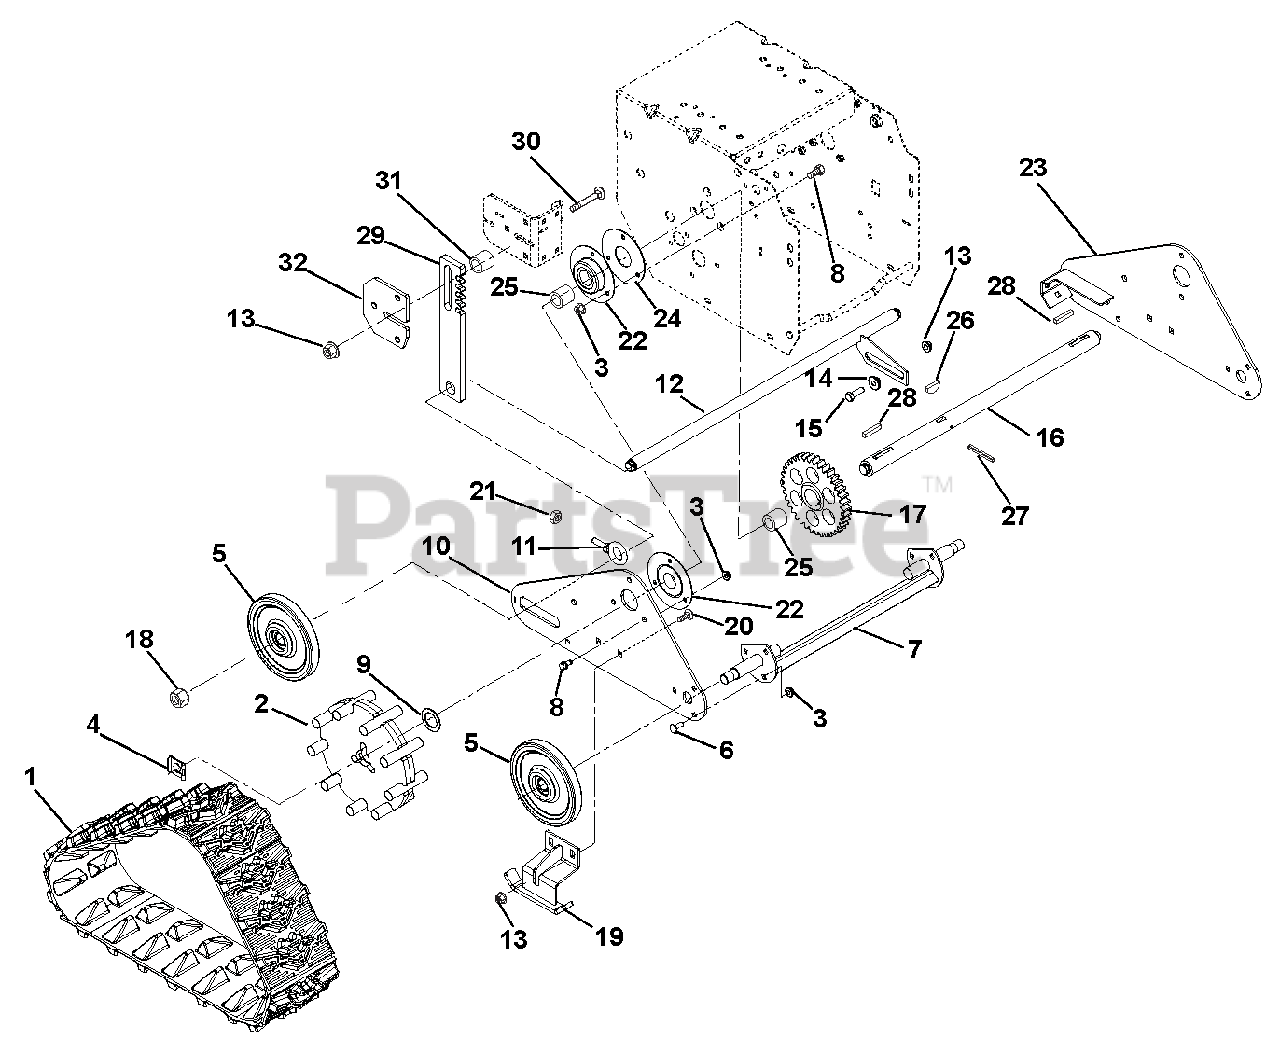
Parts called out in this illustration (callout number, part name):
1	TRACK, RUBBER
2	WHEEL, DRIVE-TRACK
3	@NUT-LK-TOP-FLG .25-20 YWZC
4	CLIP, SNAP .625 DIA
5	WHEEL, BOGIE - SINGLE BEARING
6	@BLT-RDHDSQNK .25-20X.75 G5YZ
7	AXLE, FRONT-DELUXE TRACK
8	@BLT-HEX .25-20X.75 GR5 YWZC
9	WSHR-FL-STL 1.010X1.505X.062YZ
10	SIDE PLATE, RH-DELUXE TRACK
11	BLT-EYE .375-16X.880 YWZC
12	AXLE, REAR - DELUXE TRACK
13	@NUT-LK-TOP-FLG .31-18 YWZC
14	BSHG-FLG .325X.499X.3X.875
15	@BLT-HEX .31-18X1.00 GR5 YWZC
16	AXLE, TRACK-DELUXE
17	GEAR, SPUR
18	@NUT-LK-NYL .625-18 YWZC
19	RUNNER, GUIDE-TRACK
20	@BLT-RDHDSQNK .31-18X.75 G5YZ
21	NUT-LK-CTR-FLG .38-16 YWZC
22	BRG-FLG 1.003/1.000 3 BOLT
23	SIDE PLATE, LH-DELUXE TRACK
24	PLATE, BEARING SPACER
25	BSHG-SLV, 1.012X1.125X1.00
26	KEY-WDRF .25X.750X.313 SAE91
27	PIN-ROLL .188X1.25
28	KEY-RECT .25X.188X1.00
29	STOP, HEIGHT ADJUSTER - DELUXE
30	@BLT-RHDSHSQNK.31-18X1.25 G5YZ
31	SPACER .50 X .32 X .42
32	PLATE, HEIGHT ADJUSTER
